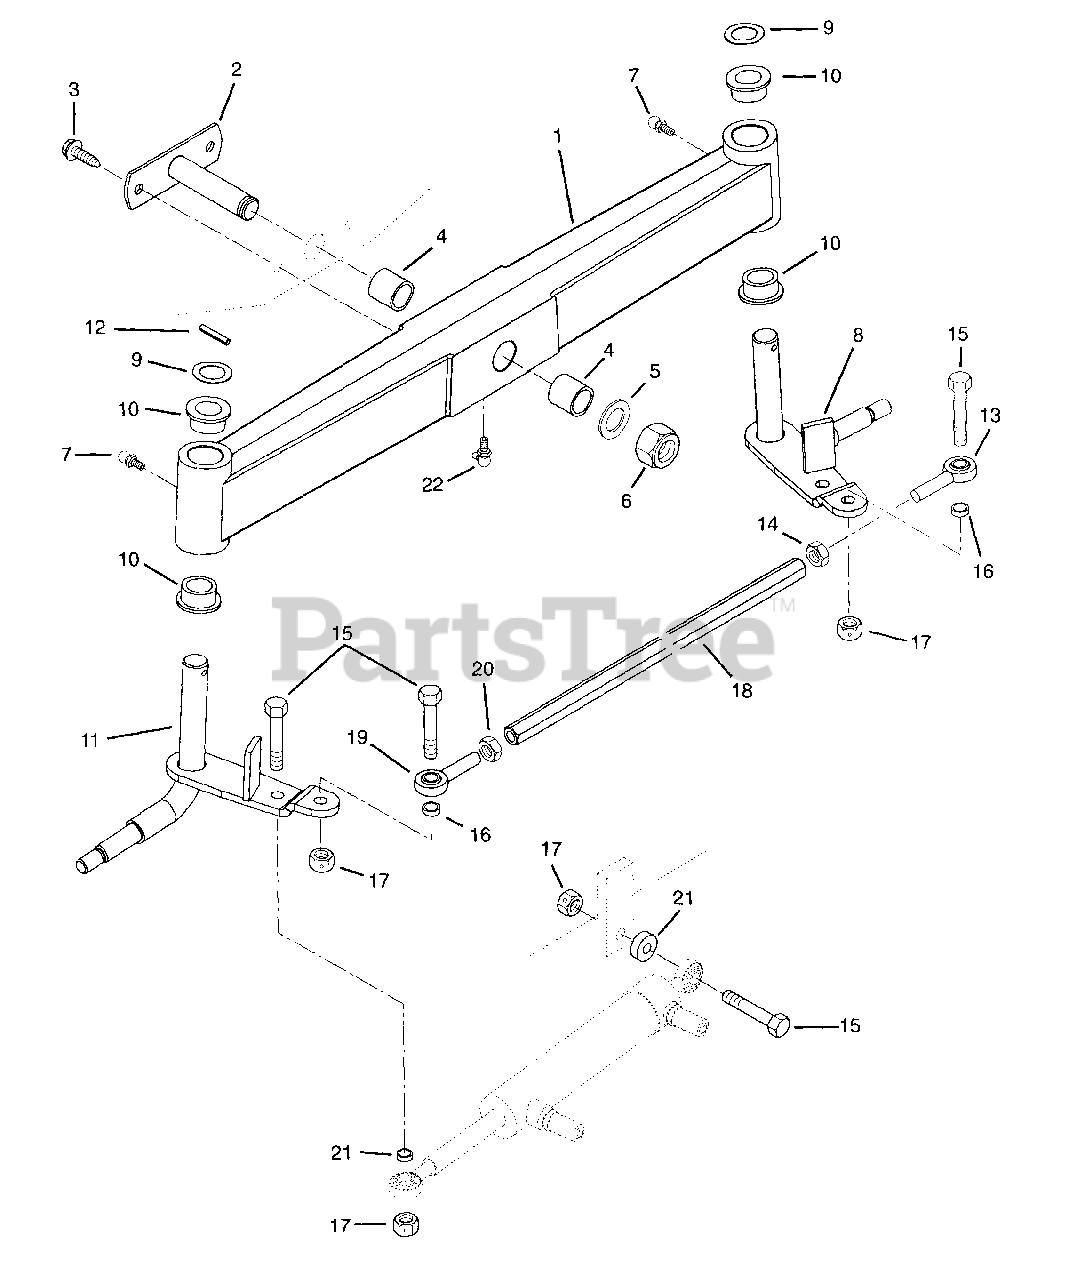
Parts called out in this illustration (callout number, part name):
1	Steering Axle
2	Weldment, Axle Pin
3	Screw-Tapping .375-16 x .75 Hex Washer Head
4	Bearing-Sleeve 1.00 x 1.25 x 1.25
5	Washer-Flat-Steel 1.010 x 1.505 x .062
6	Nut-Locking 1.0-14 Washer Insert
7	Fitting-Lube .25-28 x .256
8	Weldment, Kingpin (LH)
9	Washer-Hardened-Thrust 1.00 x 1.55 x .03
10	Bearing-Flange .020 x 1.385 x .75 x 1.75 Nylon
11	Weldment, Kingpin (RH)
12	Pin-Roll .25 x 1.50
13	Rod End, 1/2 RH
14	Nut-Hex .50-20 Grade 2
15	Bolt-Hex .50-13 x 2.00
16	Spacer .520 x .625 x .125
17	Nut-Locking-Center .50-13
19	Rod End, 1/2 LH
20	Nut-Jam .50-20 Left Hand Thread Grade 2
21	Spacer .56 x 1.00 x .420
22	Lube Fitting 90°
